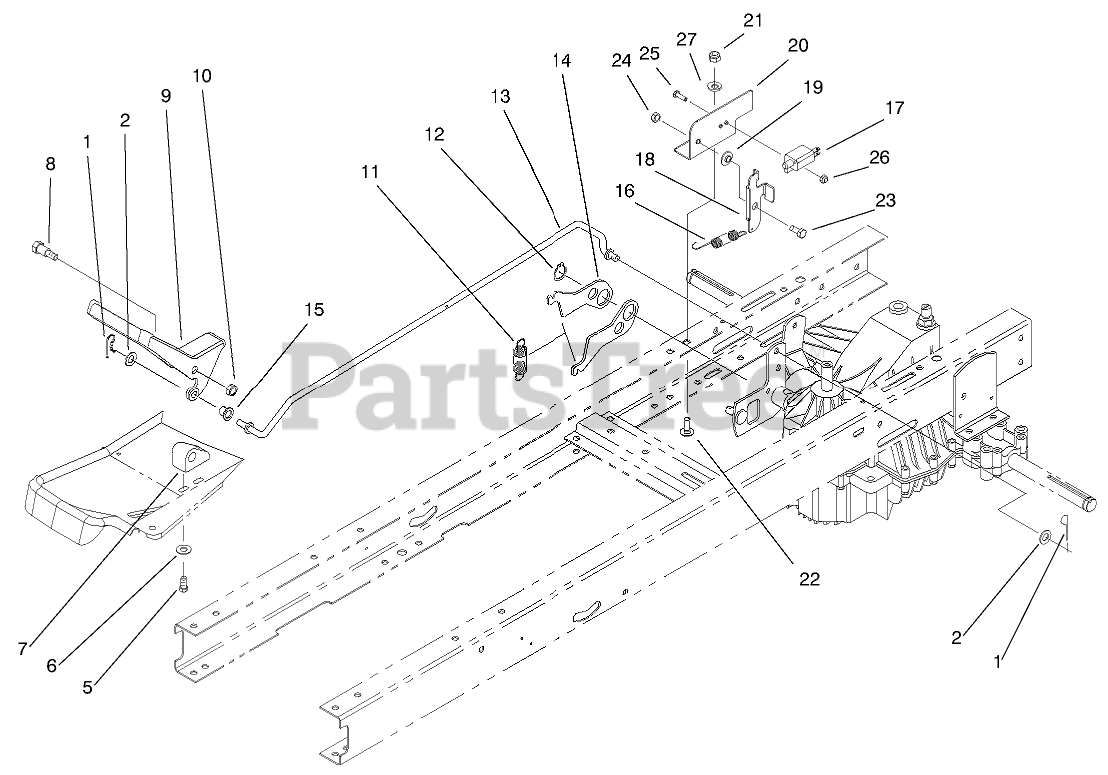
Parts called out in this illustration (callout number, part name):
1	PIN-COTTER
2	WASHER-FLAT
5	SCREW-PLASTITE
6	WASHER-FLAT
7	BLOCK-PIVOT
8	SCREW-SHOULDER, HH
9	PEDAL-CONTROL, SPEED
10	NUT-LOCK, NI
11	SPRING-EXTENSION
12	RING-SNAP
13	ROD-SPEED CONTROL,1538
14	NEUTRAL RETURN LEVER
15	BUSHING-FLANGED
16	SPRING-EXTENSION
17	SWITCH-POLE, SINGLE
18	BRACKET-PIVOT
19	WASHER-STEPPED
20	BRACKET-ADJUSTMENT
21	NUT-LOCK, NI
22	SCREW-CARR
23	SCREW-HHF
24	NUT-LOCK, NI
25	SCREW-SHH
26	NUT-LOCK
27	WASHER-PLAIN
